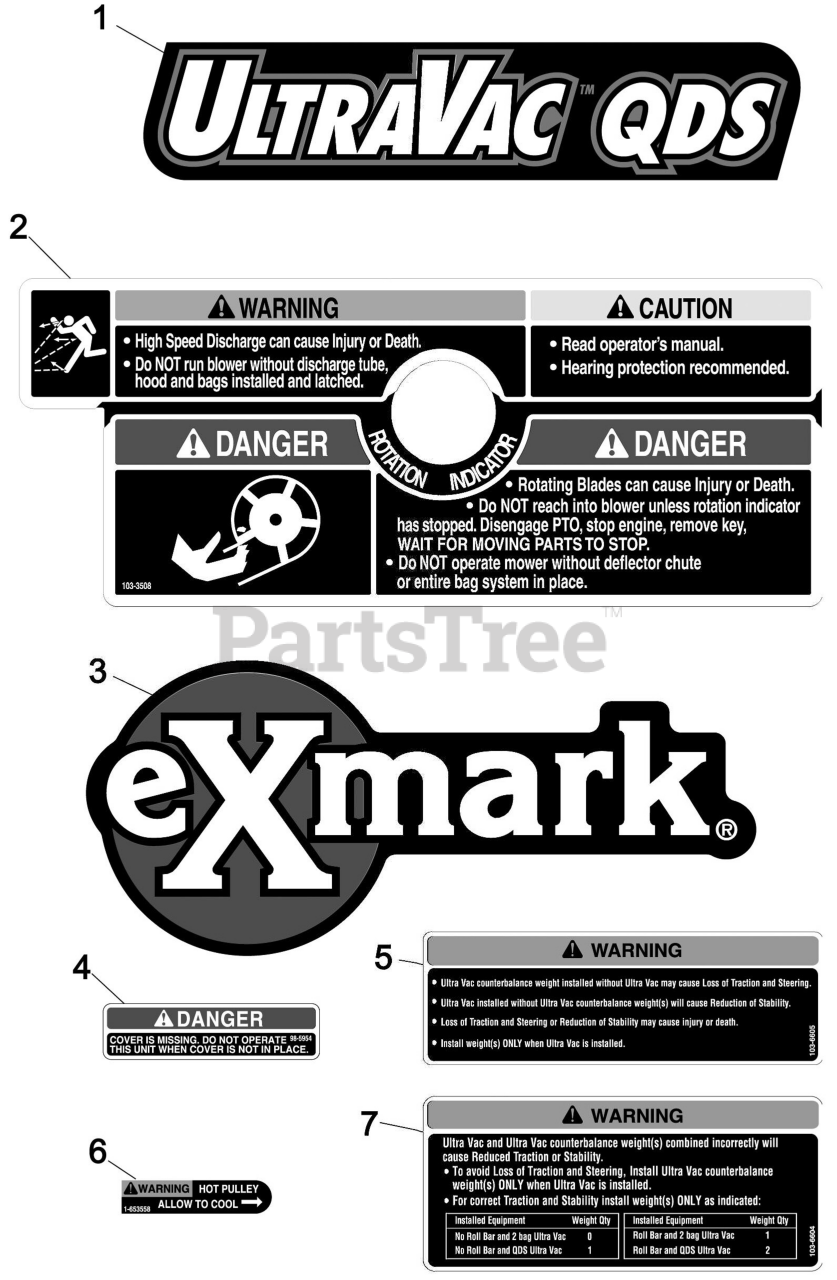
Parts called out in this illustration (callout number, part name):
1	DECAL, ULTRAVAC
2	DECAL-WARNING
3	DECAL, EXMARK LOGO
4	DECAL-COVER, MISSING
5	DECAL,WEIGHT
6	DECAL-WARNING
7	DECAL,WEIGHT
